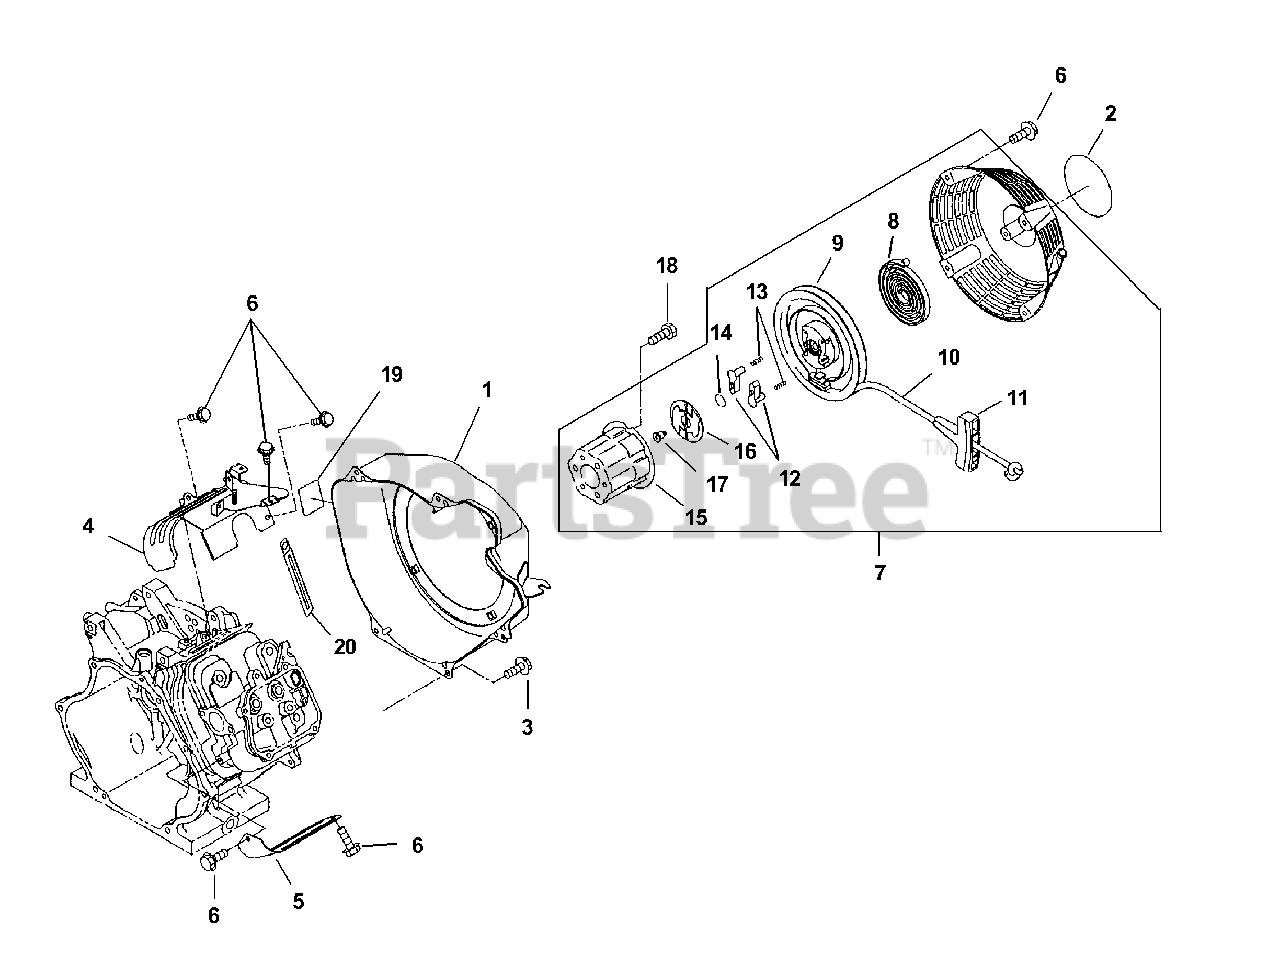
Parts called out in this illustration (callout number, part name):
1	Blower housing
2	Label (trademark)
3	Flange bolt
4	Cylinder baffle 1 UN
5	Cylinder baffle 2
6	Flange bolt
7	Recoil starter assy
8	Spring rewind
10	Starter rope
11	Starter knob
13	Friction spring
14	Return spring
16	Ratchet guide
17	Set screw
19	Label (warning)
